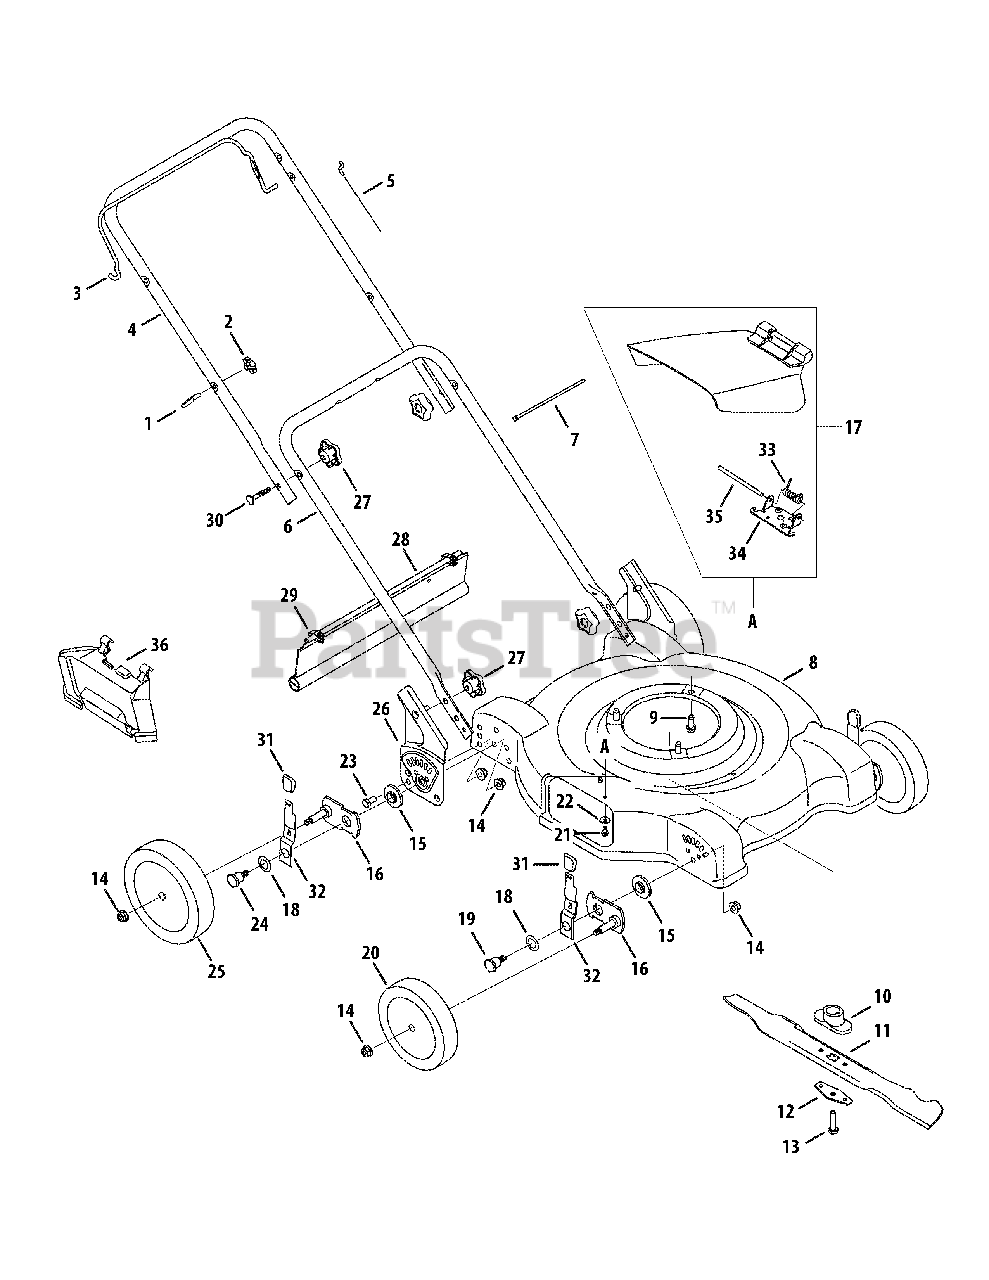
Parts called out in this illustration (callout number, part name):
1	Eye Bolt
2	Wing Nut
3	Blade Control
4	Upper Handle
5	Control Cable
7	Cable Tie
8	Deck Assembly, 22" (w/Sprig)
8	Deck Assembly, 22" (No Sprig)
9	TT Screw, 3/8-16 x 1.0
10	Blade Adapter
11	Standard Blade, 22"
11	Mulching Blade, 22"
12	Blade Bell Support
13	Screw, 3/8-24 x 1.5
14	Lock Nut, 3/8-16
15	Height Adjuster Bearing
16	Pivot Arm
17	Hinged Chute Deflector Assembly
18	Bell Washer, .760 OD x 1.25 OD
19	Shoulder Screw
20	Front Wheel, 7 x 1.8, Bar
21	TT Screw, 1/4-20 x .5
22	Bell Washer, .265 ID x .75 OD
23	Screw, 3/8-16 x .75
24	Shoulder Screw
25	Rear Wheel, 8 x 1.8, Bar
26	Handle Bracket Assembly, RH
26	Handle Bracket Assembly, LH
27	Star Knob
28	Trailshield
29	Hinge Clip
30	Carriage Bolt, 5/16-18 x 2
31	Knob
32	Lever
33	Torsion Spring
34	Chute Hinge
35	Hinge Pin
36	Mulching Baffle
